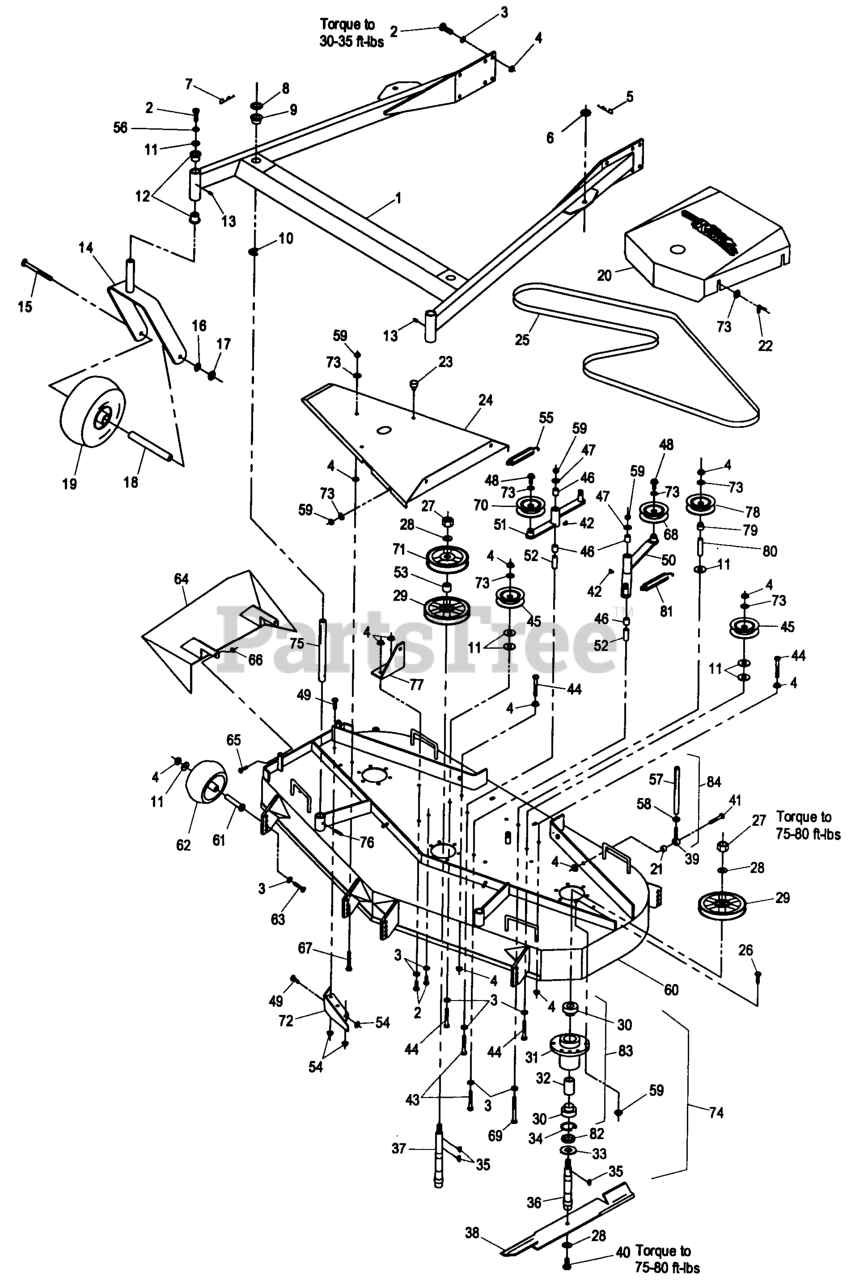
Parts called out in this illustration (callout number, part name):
1	SUPPORT ASSY-FMD60
5	PIN,HAIR COTTER
8	SPACER-DECK SUPPORT
9	BUSHING-DECK
11	WASHER
12	BEARING-FLANGED
22	NUT-WING
24	WLD,DECK COVER
25	BELT-DRIVE, BLADE
28	WASHER-SPRING
29	SHEAVE,BLADE DRIVE
30	BEARING
32	SPACER-BEARING
33	GUARD-BEARING, BOTTOM
36	SHAFT,SPINDLE SHORT
37	SHAFT,SPINDLE LONG
39	BALLJOINT
43	SCREW-HH
45	IDLER,PULLEY
46	SLEEVE-BEARING
50	Arm, Deck Drive Idler
51	Arm, Deck Idler
52	BUSHING-PIVOT, IDLER
53	SPACER-TUBE
55	SPRING-EXTENSION
57	LINK, DECK SUPPORT
61	BUSHING-ROLLER
62	ROLLER-SCALP, ANTI
68	PULLEY-IDLER
70	IDLER,PULLEY
72	WLD,BAFFLE DISCHARGE
74	CUTTER HOUSING ASM,OUTER
75	ROD,DECK SUPPORT
77	BRACKET,SPRING ANCHOR
78	PULLEY-IDLER
79	BUSHING,IDLER
80	SPACER-FENDER
81	SPRING-EXTENSION
82	SPACER-PULLEY/BEARING
